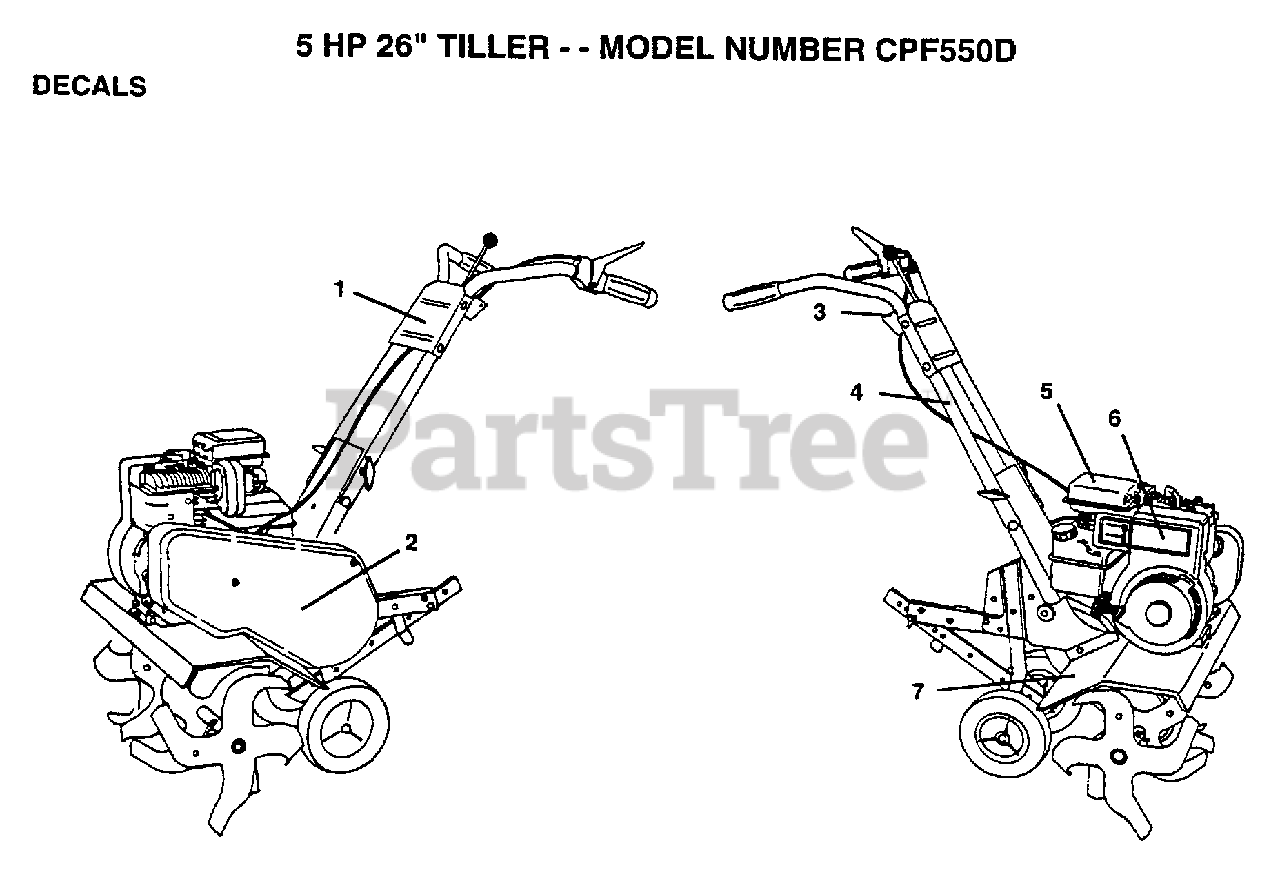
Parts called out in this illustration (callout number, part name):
1	DECAL, HP, REVERSE
2	DECAL, LOGO
3	DECAL REVERSE
4	DECAL TI
7	DECAL TI
